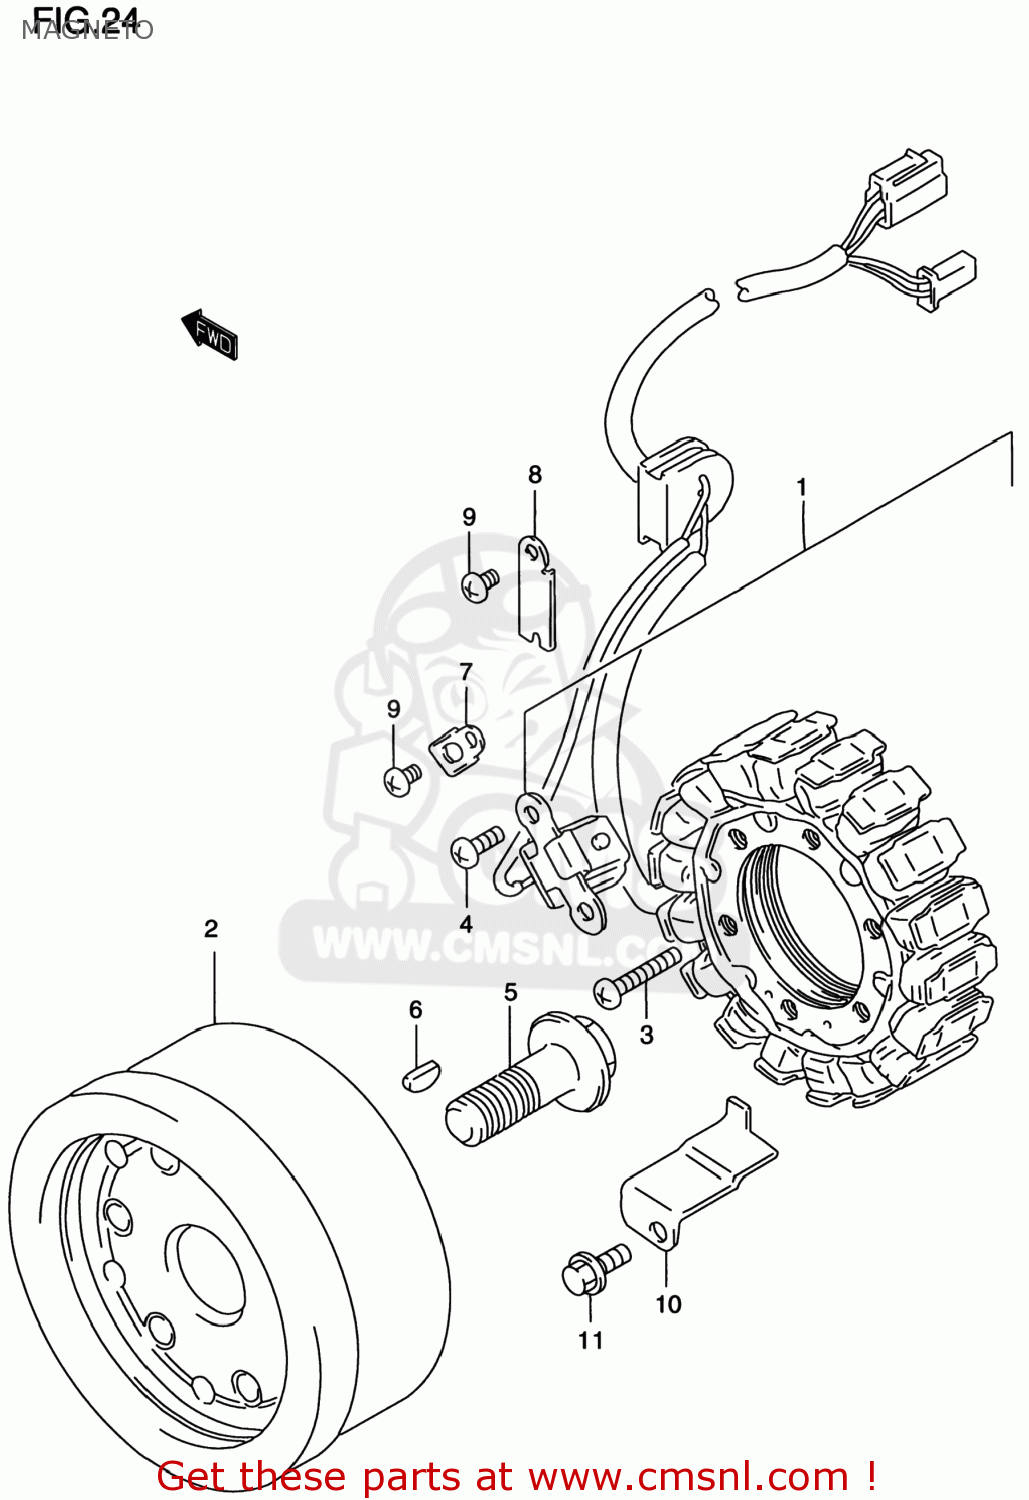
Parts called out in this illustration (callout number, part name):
1	STARTER ASSY
2	ROTOR ASSY
3	BOLT,G/S SWITC
4	SCREW
5	BOLT(14X43)
6	KEY
7	CLAMP,GENERATOR LEAD WIRE
8	CLAMP NO.1,MAGNETO READ WIRE
9	SCREW
10	CLAMP,MAGNETO LEAD WIRE
11	BOLT
